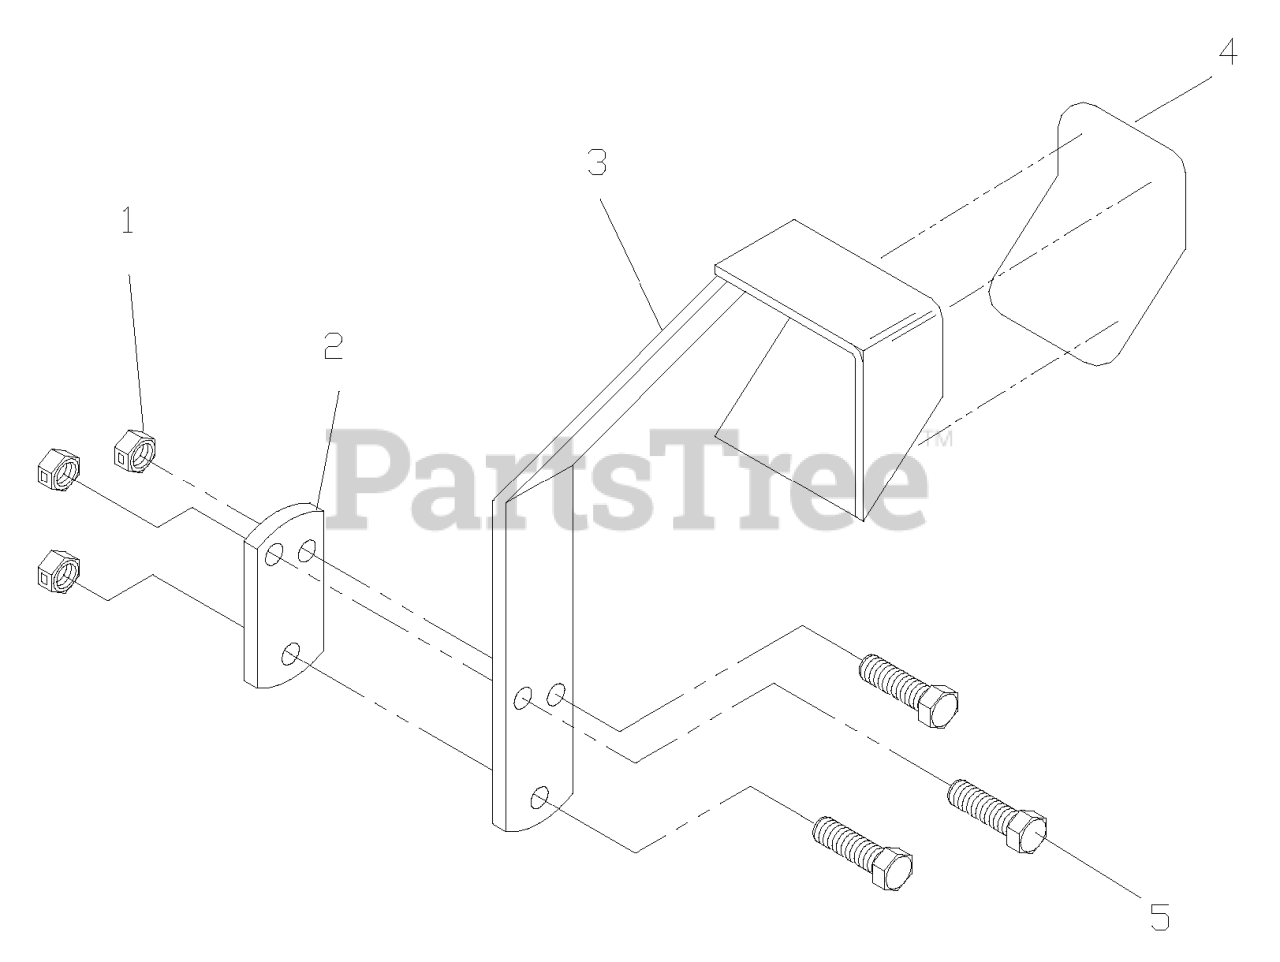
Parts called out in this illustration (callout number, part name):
1	NUT 3/8-16 NYLOC
2	TIGHTENING PLATE BLK
3	LIFT PEDAL BLK
4	ANTI-SKID PAD
5	HCS 3/8C X 1 1/2
